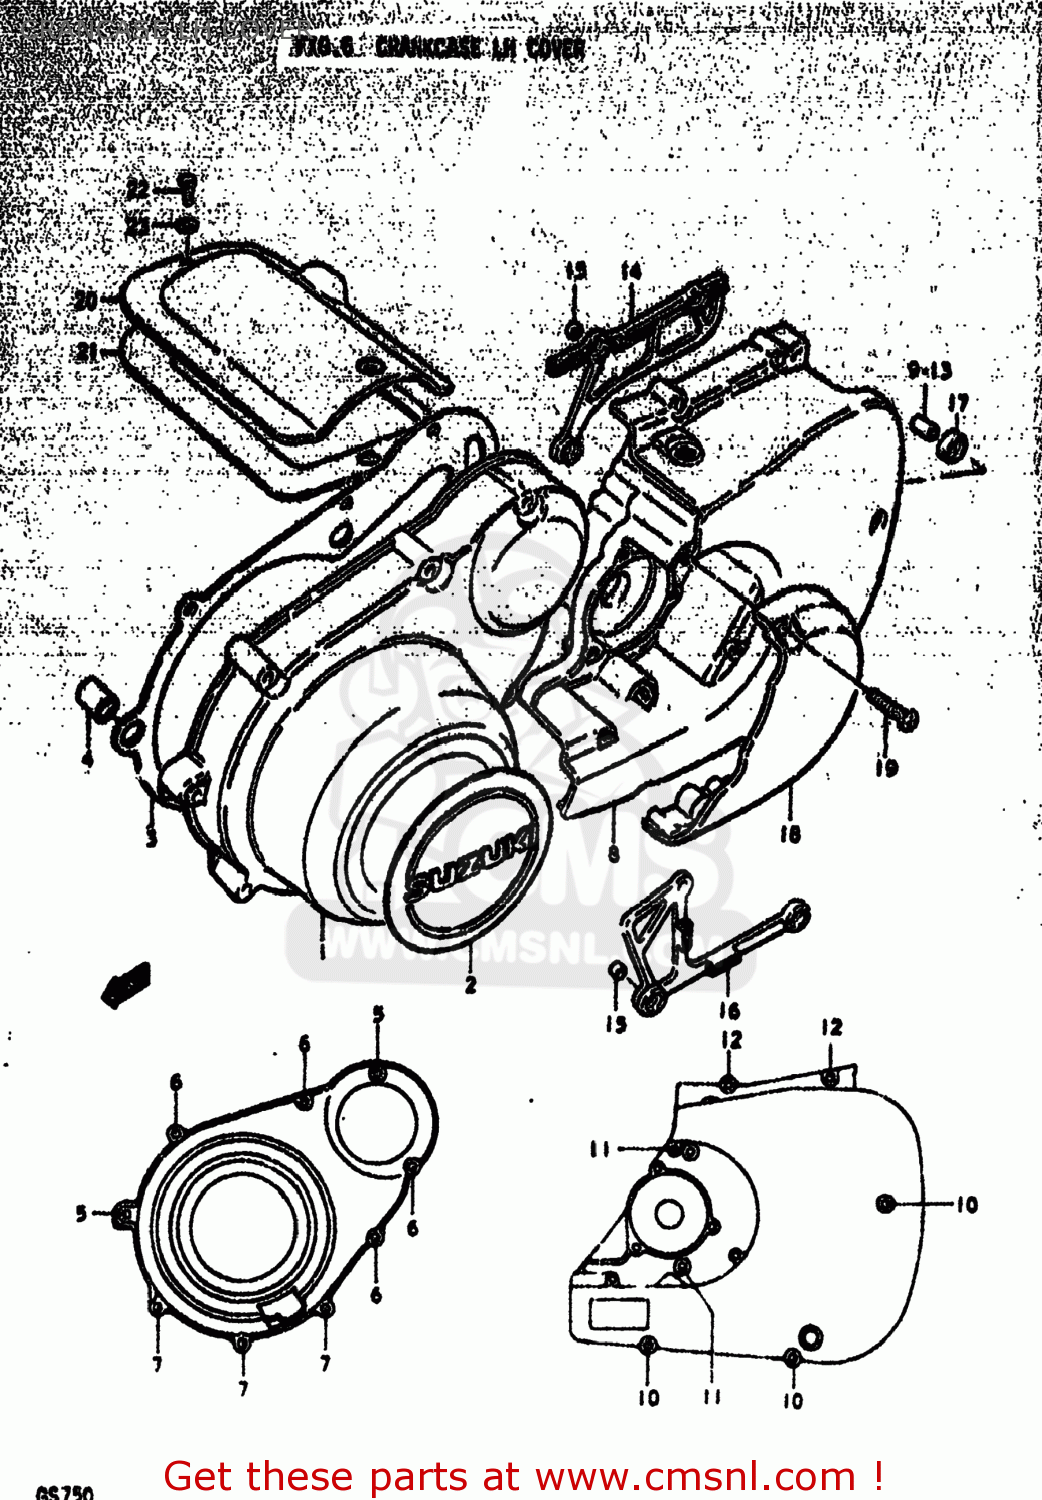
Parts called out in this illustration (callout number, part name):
1	COVER
2	EMBLEM
3	GASKET,MAGNETO COVER (MCA)
4	PIN
5	SCREW (6X45)
6	SCREW
7	SCREW (6X35)
8	COVER,SPROCKET
9	PIN
10	SCREW 6X85
11	SCREW (6X45)
12	SCREW
13	SPACER
14	GASKET (NAS)
15	SPACER
16	GASKET (NAS)
17	CUSHION,ENGINE SPROCKET
18	CAP,CLUTCH RELEASE ADJUST
19	SCREW
20	COVER,STARTER MOTOR
21	GASKET,STARTER MOTOR COVER (NAS)
22	BOLT
23	WASHER
